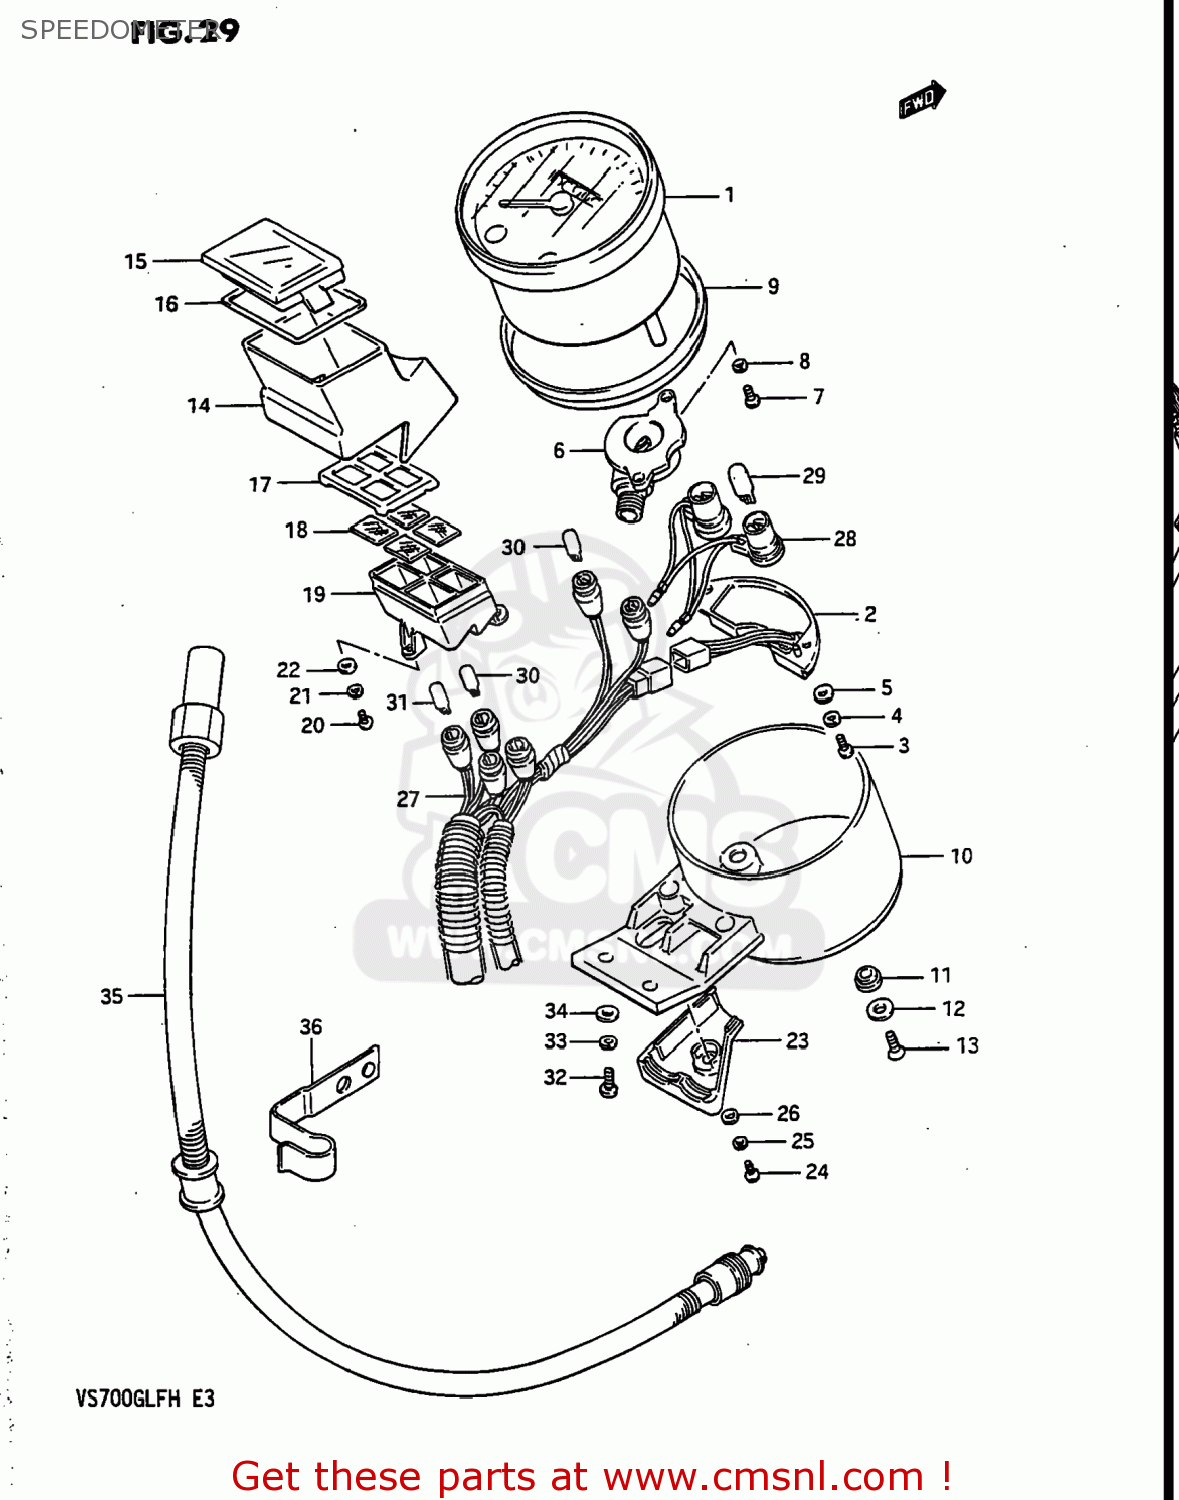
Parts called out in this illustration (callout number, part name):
1	SPEEDOMETER ASSEMBLY
2	UNIT,WATER TEMP WARNING
3	SCREW
4	LOCK WASHER
5	WASHER 3.3X8X0
6	BOX,GEAR
7	SCREW 4X10
8	LOCK WASHER
9	CUSHION,METER
10	COVER,METER
11	CUSHION,METER
12	WASHER
13	SCREW
14	BOX,PILOT LAMP
15	LENS,PILOT BOX
16	CUSHION
17	PLATE,PILOT LENS
18	LENS SET
19	CASE,PILOT LAMP
20	SCREW
21	LOCK WASHER
22	WASHER 3.3X8X0
23	COVER,PILOT BOX
24	SCREW
25	LOCK WASHER
26	WASHER 4MM
27	SOCKET,METER
28	SOCKET,METER NO.2
29	BULB(12V3.4W,T10)
30	BULB(12V3W,T6.5)
31	BULB(12V1.7W,T6.5)
32	SCREW
33	WASHER,LOCK
34	WASHER
35	CABLE ASSEMBLY,SPEEDOMETER
36	GUIDE,SPEEDOMETER CABLE
